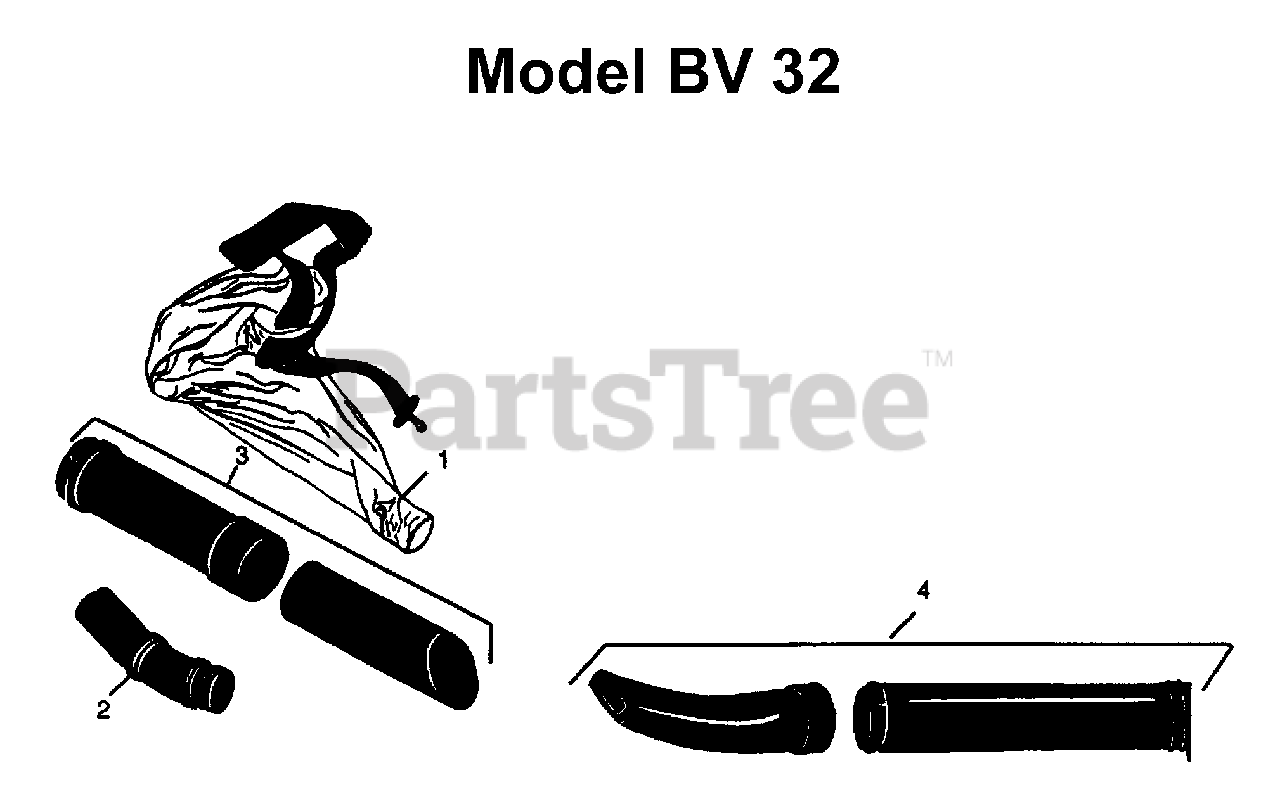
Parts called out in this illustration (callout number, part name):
1	COLLECTION BAG W/ STRAP
2	ELBOW TUBE
3	VAC TUBE SET
4	TUBE & NOZZLE ASS'Y
